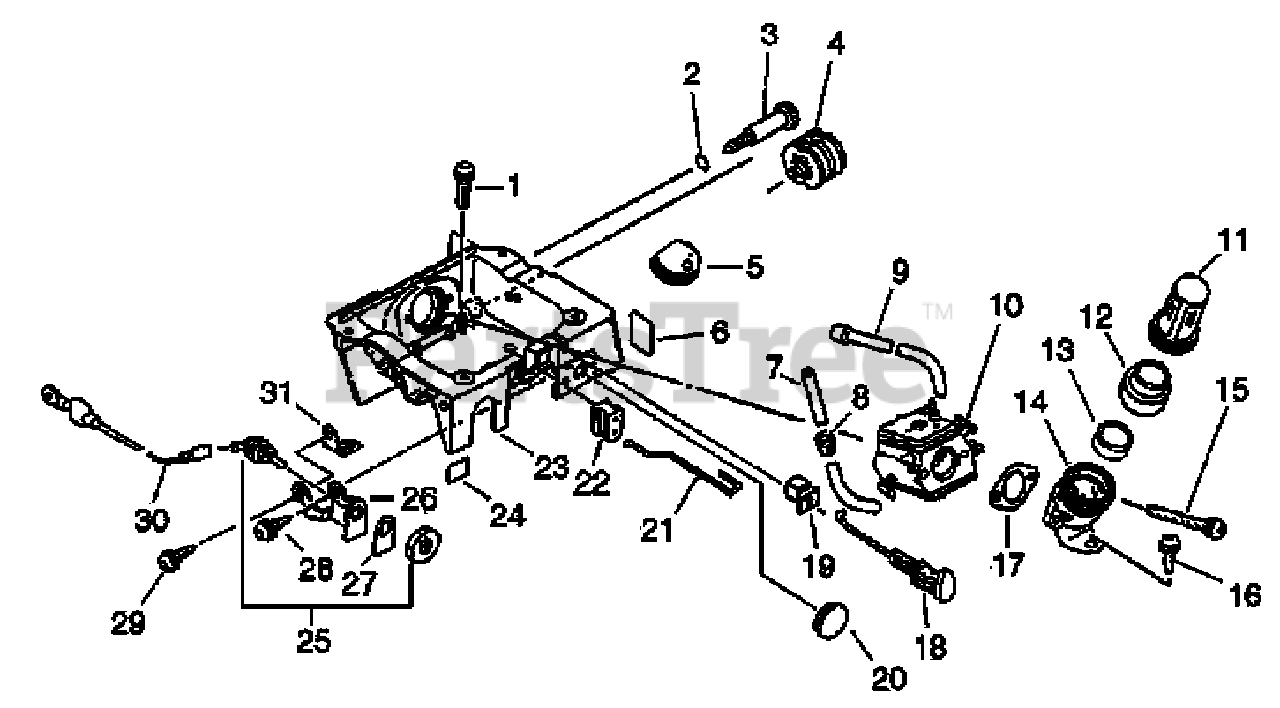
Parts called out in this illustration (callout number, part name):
1	SCREW - 5X20
2	O-RING - 7
3	SCREW, IDLE ADJUST
5	GROMMET
6	LABEL - IDLE
7	PIPE - 3X6X130
8	GROMMET
9	PIPE - IMPULSE
10	CARBURETOR HDA-216
11	SCREEN, DEBRIS
12	CUSHION
13	COLLAR - 22
14	ADAPTOR, INTAKE
15	SCREW - 5X53
16	SCREW - 5X14
17	GASKET, INTAKE
18	ROD, CHOKE
21	ROD, THROTTLE
22	GUIDE, THROTTLE ROD
23	CASE, CARBURETOR
24	LABEL - STOP
25	IGNITION SWITCH ASSY
26	BRACKET, SWITCH
27	LABEL - SWITCH
28	SCREW - 5X10
29	SCREW - 4X10
30	LEAD - GROUND
31	TERMINAL - GROUND
